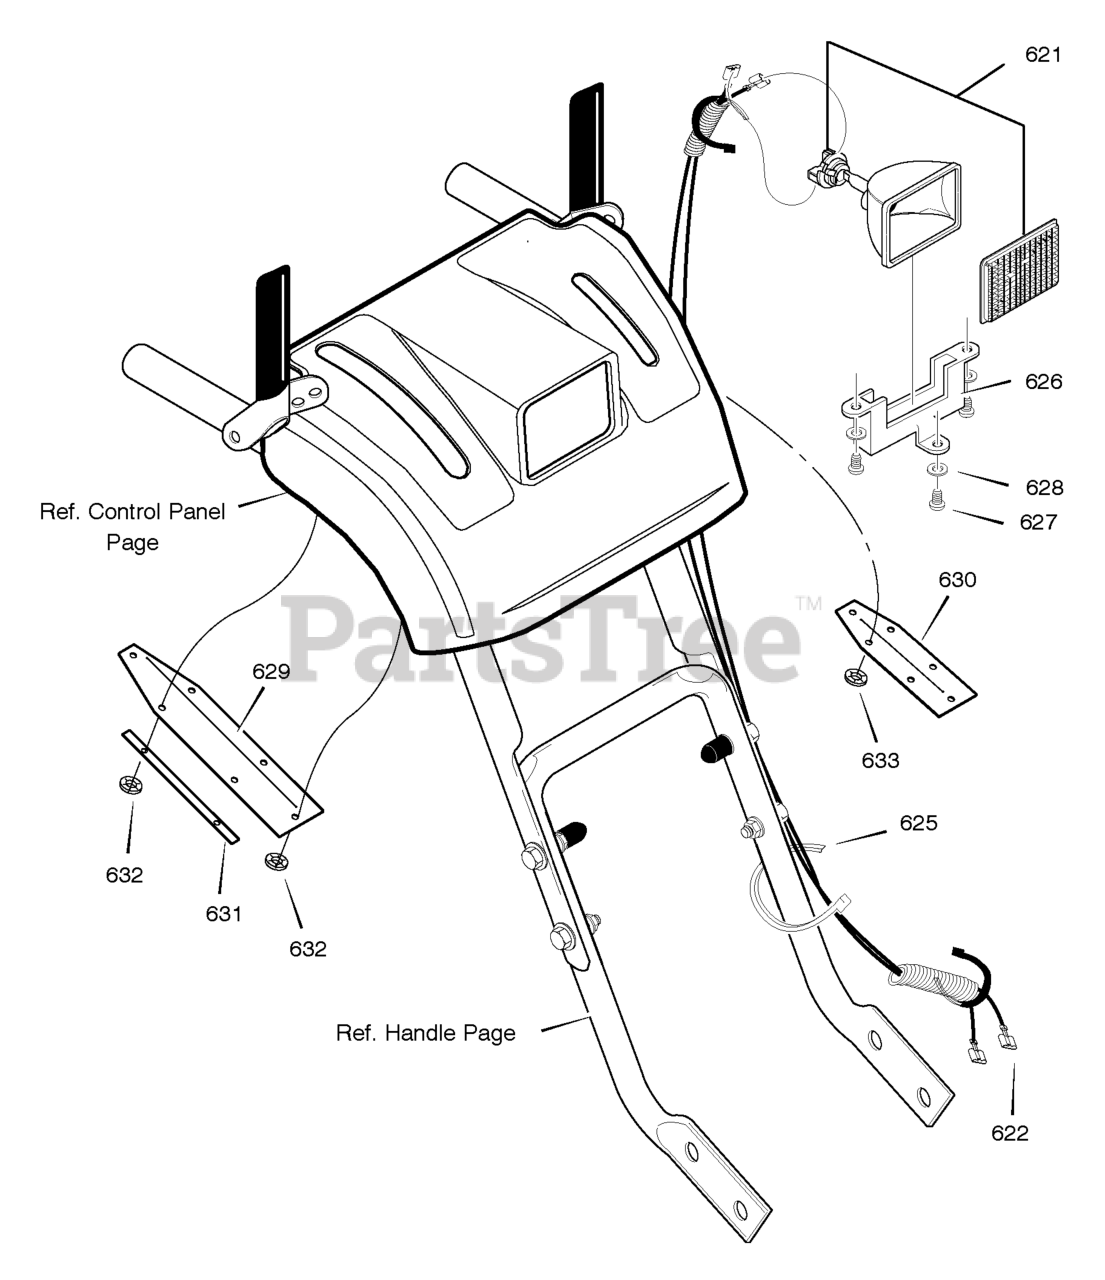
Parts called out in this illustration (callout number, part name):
621	LIGHT, HALOGEN
622	HARNESS, WIRE
625	TIE, CABLE
626	BRACKET, LIGHT
627	SCREW #8 X .50
628	WASHER, FLAT
629	COVER, SPEED CONTROL
630	COVER, REMOTE CONTROL
631	FRAME, SPEED CONTROL
633	NUT, PUSH
